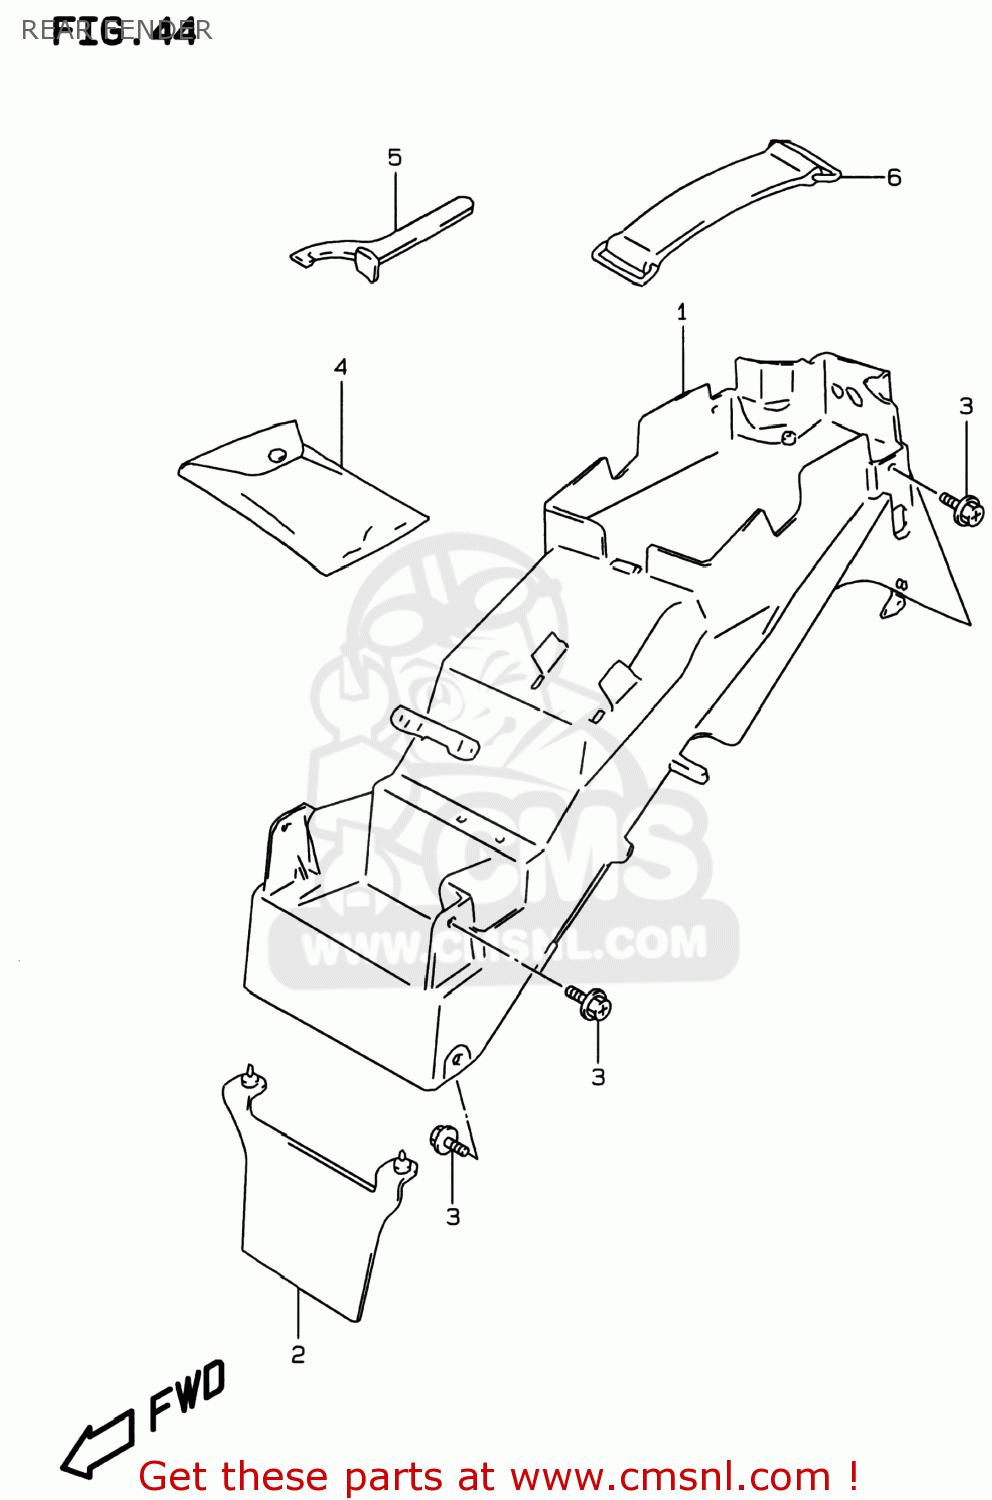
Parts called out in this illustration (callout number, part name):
1	FENDER,REAR
2	MUDGUARD,RR FENDER FR
3	BOLT(6X16)
4	TOOL ASSY
5	CLAMP
6	BAND
